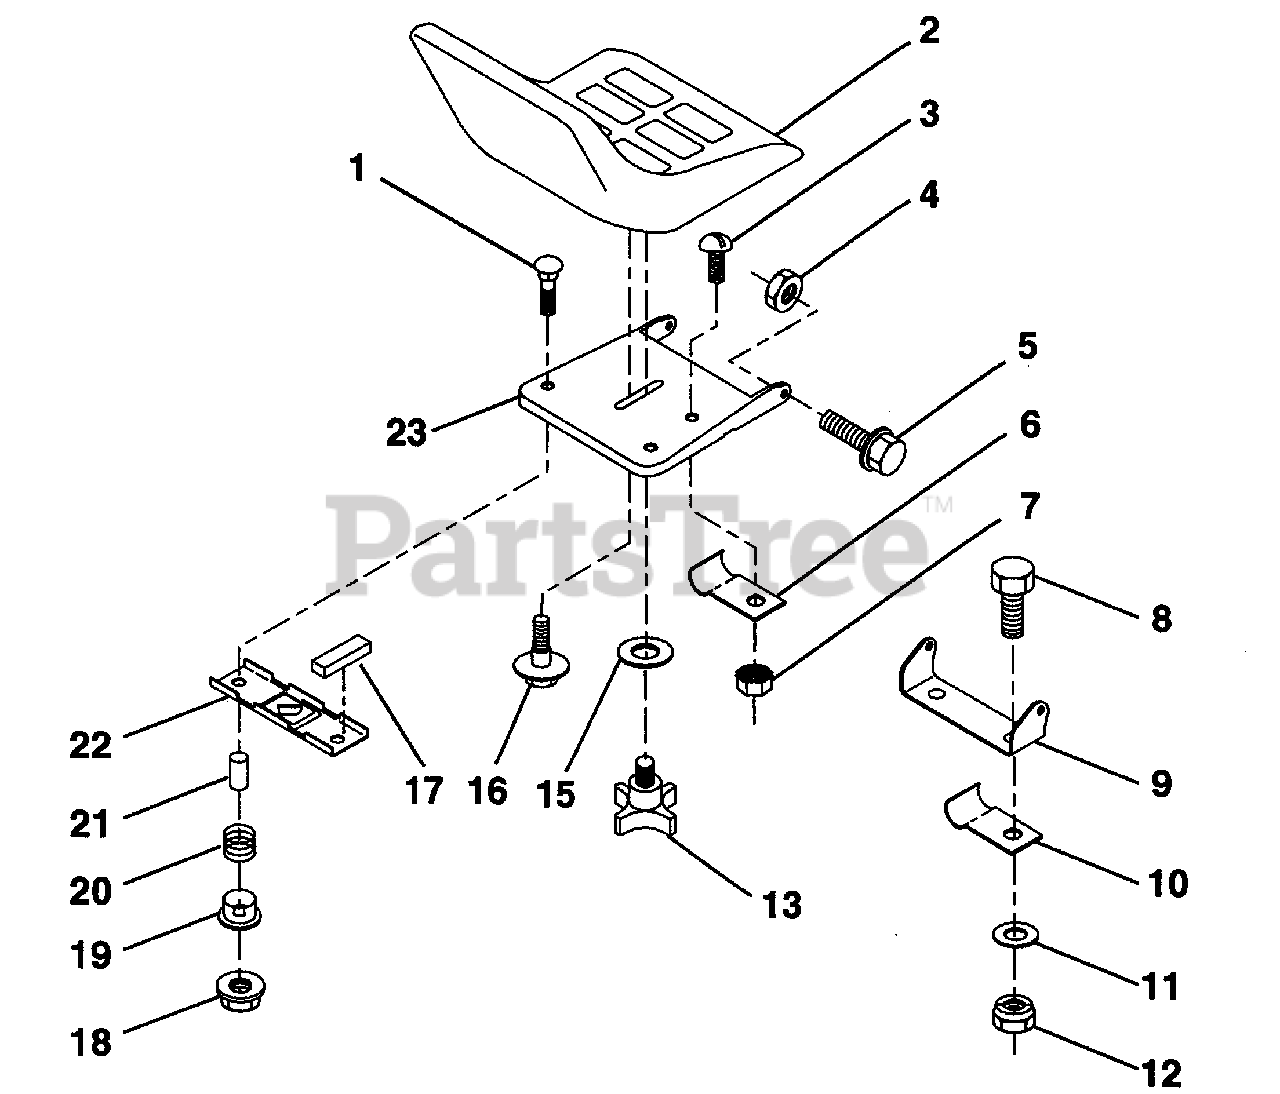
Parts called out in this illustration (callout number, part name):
1	Bolt, Carriage 1/4-20 x 1-3/8
2	Seat (AYP part number)
3	Screw, Slotted Pan Head #10-32 x 1/2 (AYP part number)
4	Nut, Crownlock 5/16-18
5	Bolt, Shoulder 5/16-18 UNC (AYP part number)
6	Clip, Insulated (AYP part number)
7	Nut, Keps #10-32 UNF (AYP part number)
8	Bolt, Hex, Fin 3/8-16 UNC x 3/4 (AYP part number)
9	Bracket, Pivot, Seat (AYP part number)
10	Clip, Insulated (AYP part number)
11	Washer 13/32 x 2 x 10 Gauge (AYP part number)
12	Nut, Crownlock 3/8-16 UNC
13	Bolt, Hex, Fin 1/2-13 UNC x 1 (AYP part number)
15	Washer 17/32 x 1-3/16 x 12 Gauge (AYP part number)
16	Bolt, Shoulder (AYP part number)
17	Strip, Foam (AYP part number)
18	Locknut, Hex, Large, Flange (AYP part number)
19	Bushing, Snap (AYP part number)
20	Spring, Compression (AYP part number)
21	Spacer, Split, Large .28 Id. x .88 (AYP part number)
22	Bracket, Switch, Mounting (AYP part number)
23	Pan, Seat (AYP part number)
